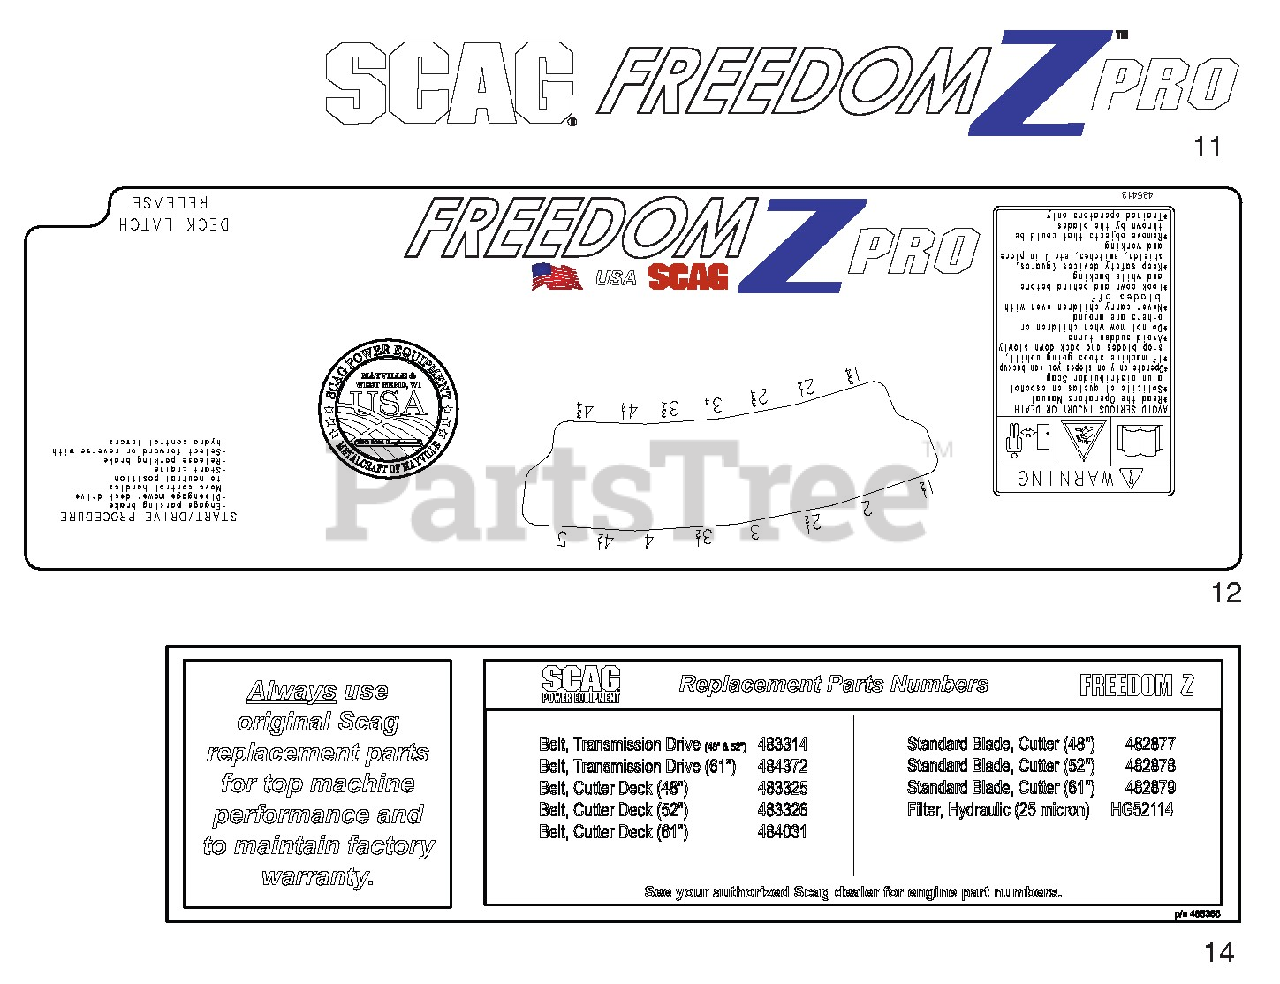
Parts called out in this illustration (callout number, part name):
11	Decal, Front SFZ Pro
12	Decal, Cutting Height - SFZ Pro
14	Decal, SFZ Replacement Parts
